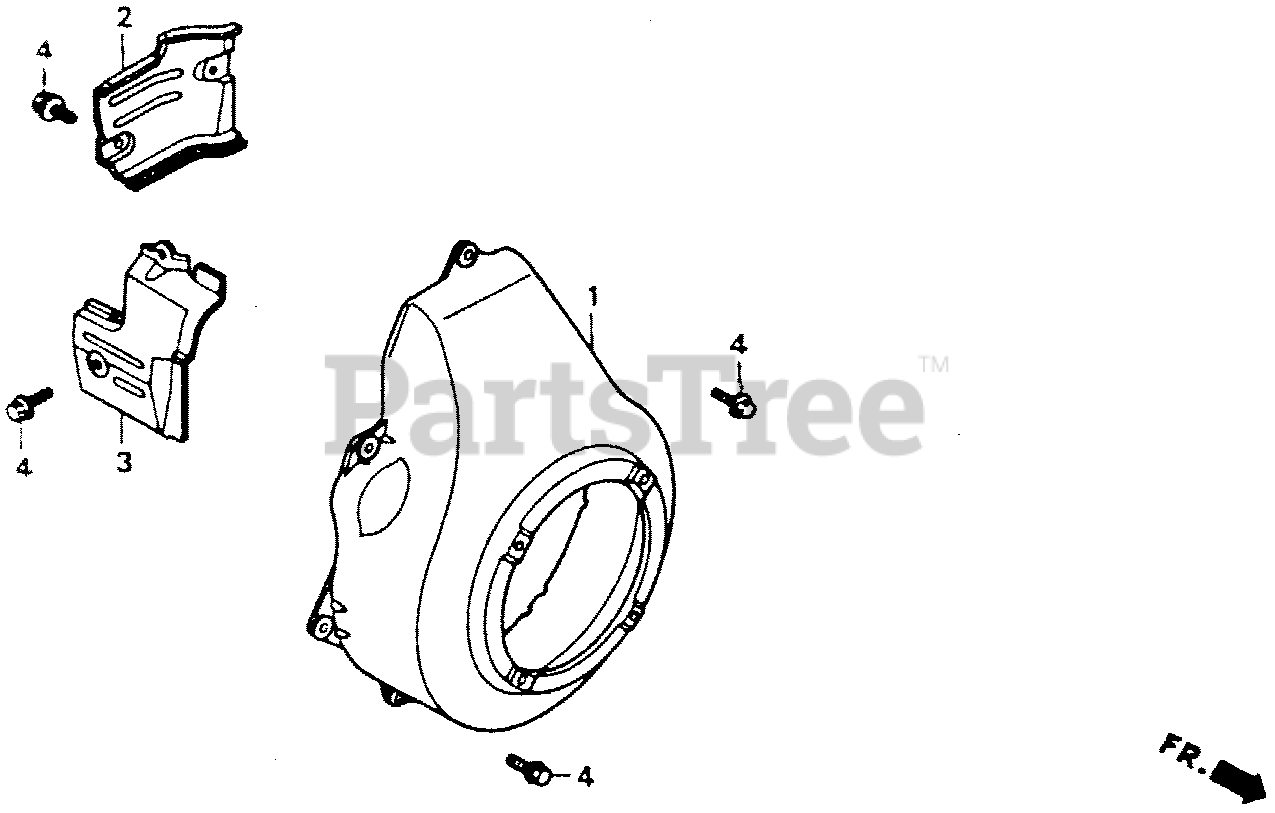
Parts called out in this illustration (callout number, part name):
1	COVER, FAN *NH116M* (URBAN SILVER METALLIC)
2	SHROUD (A)
3	SHROUD (B)
4	BOLT, FLANGE (6X12)
